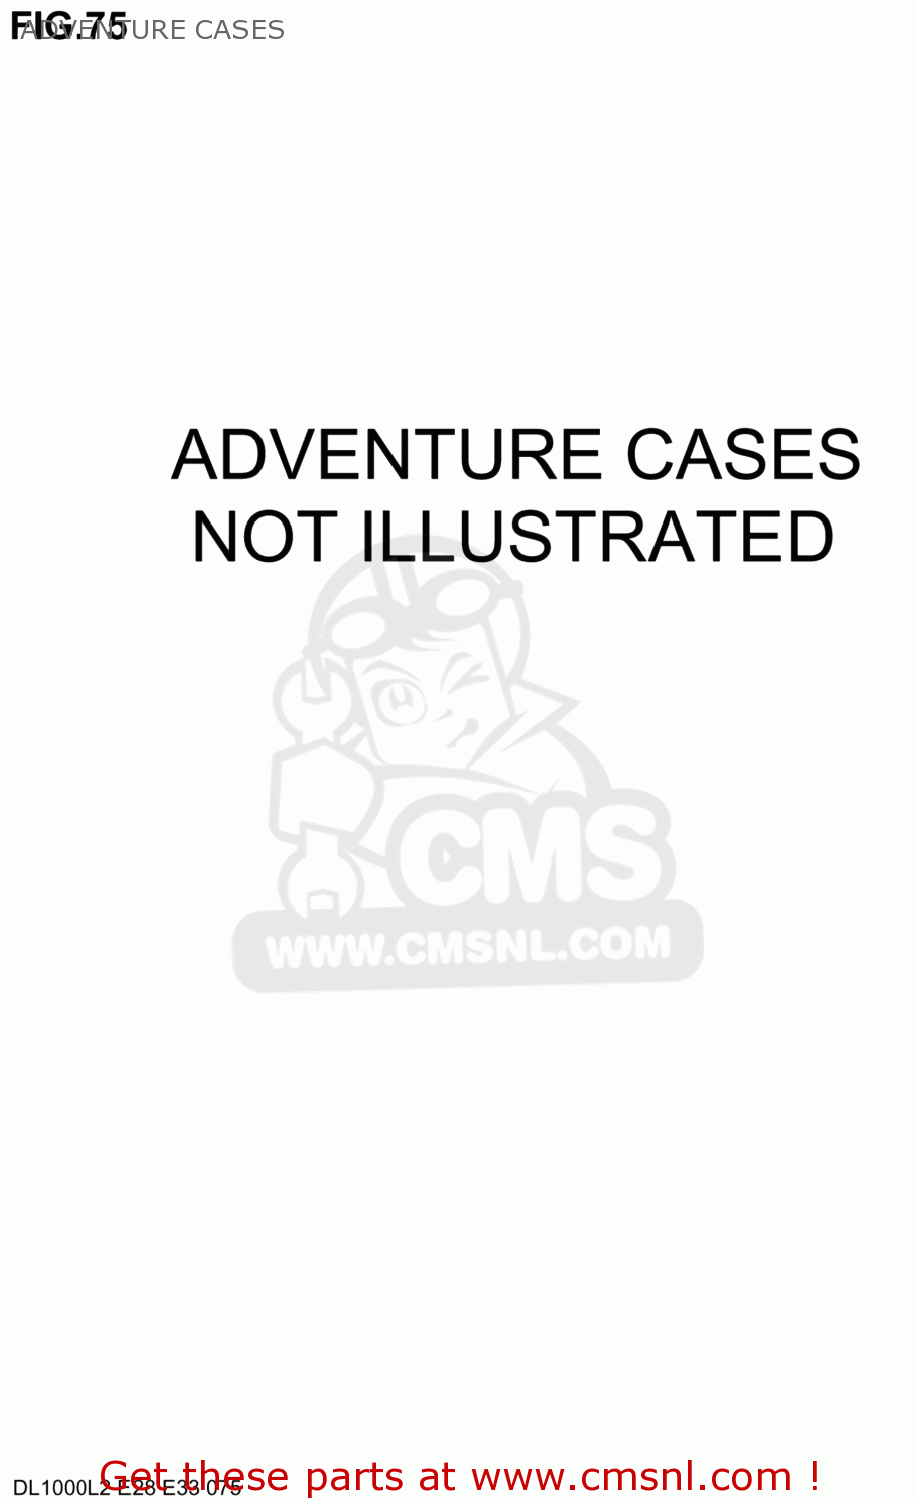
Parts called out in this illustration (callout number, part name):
1	DL1000 SIDE CAS
2	SINGLE SIDEBAG
3	EDGECOVERSET
4	CENTERCOVER YA
5	REFLECTOR SIDECASES DL650/1000 (990D0-06GSC-REF)
6	DL650 ADV S/C R
7	SINGLELOCK TC4
8	LOCKSET CASES
9	HOOK GR,SC35L
10	DL6/1 TOPCASEBL
11	T.CASECOVER YA
12	SINGLELOCK TC4
13	SIDE CASE CARR
14	DL1K S/C BRKT,
15	DL1K S/C BRKT,
16	DL1K ADV S/C HD
17	FIXINGSET SCAS
18	TOPCASE CARRIE
19	DL1K ADV T/C HD
20	FIXING SET, TO
